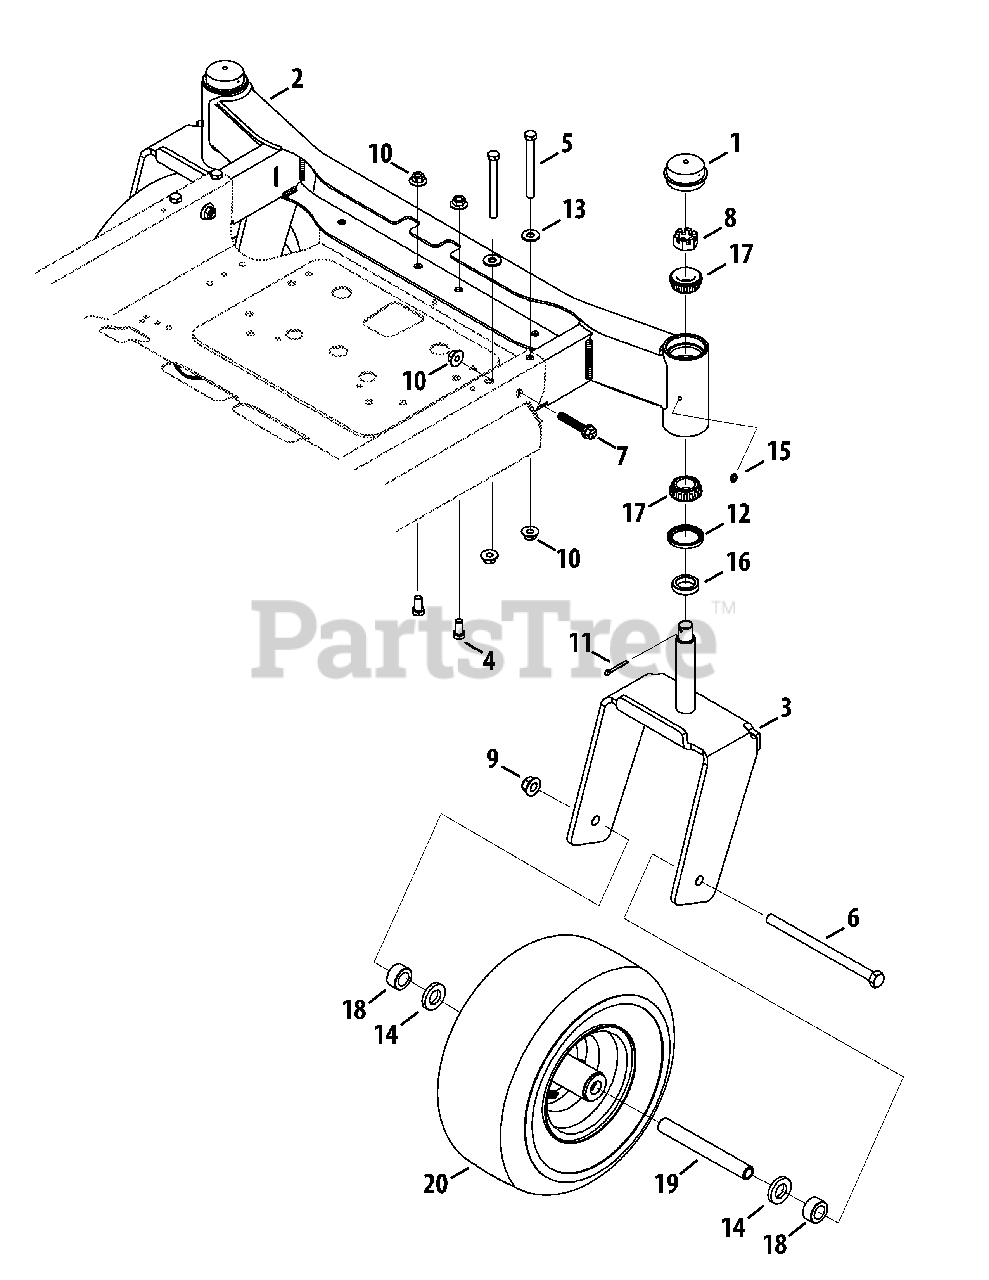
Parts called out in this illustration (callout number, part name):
1	Cap
2	Front Axle
3	Caster Wheel Bracket
4	Hex Cap Screw, 3/8-16 x .75
5	Hex Cap Screw, 3/8-16 x 3.75
6	Hex Cap Screw, 1/2-13 x 8.50
7	Hex Flange Screw, 3/8-16 x 2.00
8	Slotted Nut, 3/4-16
9	Flange Lock Nut, 1/2-13
10	Flange Lock Nut, 3/8-16
11	Cotter Pin, 5.32 x 1.25
12	Seal, 35 x 47 x 5
13	Flat Washer, .385 x .870 x .092
14	Thrust Washer, .760 x 1.50 x .060
15	Grease Fitting, 3/16
16	Seal, 1.378 x .984 x .329
17	Bearing, 47mm x 25mm x 15mm
18	Spacer, .77 ID x 1.13 OD x .56
19	Spacer, .51 ID x .75 OD x 7.10
20	Wheel Assembly, 13 x 6.5 x 6
